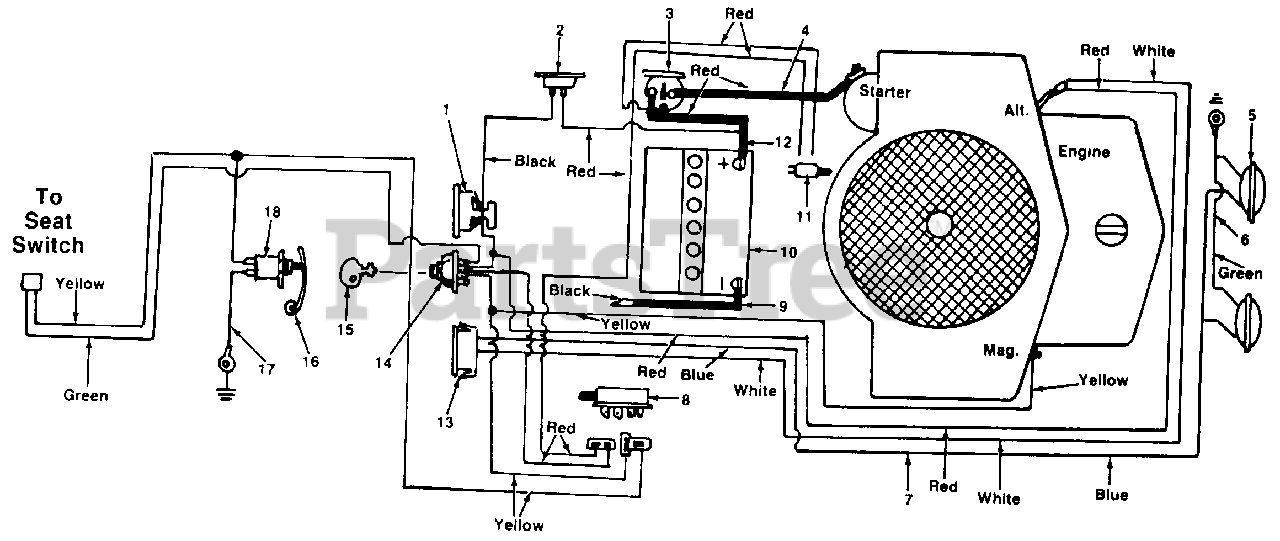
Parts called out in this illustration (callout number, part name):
1	Ammeter
2	Circuit Breaker
3	Solenoid
5	Headlight
6	Ground Wire
7	Wire Harness
8	Safety Switch
9	6 Ga. Black Wire
10	Battery 12V
11	Safety Switch
12	Wire
13	Light Switch
14	Ignition Switch
15	Ignition Key
16	Spring Lever
17	Electric Wire
18	Safety Switch
